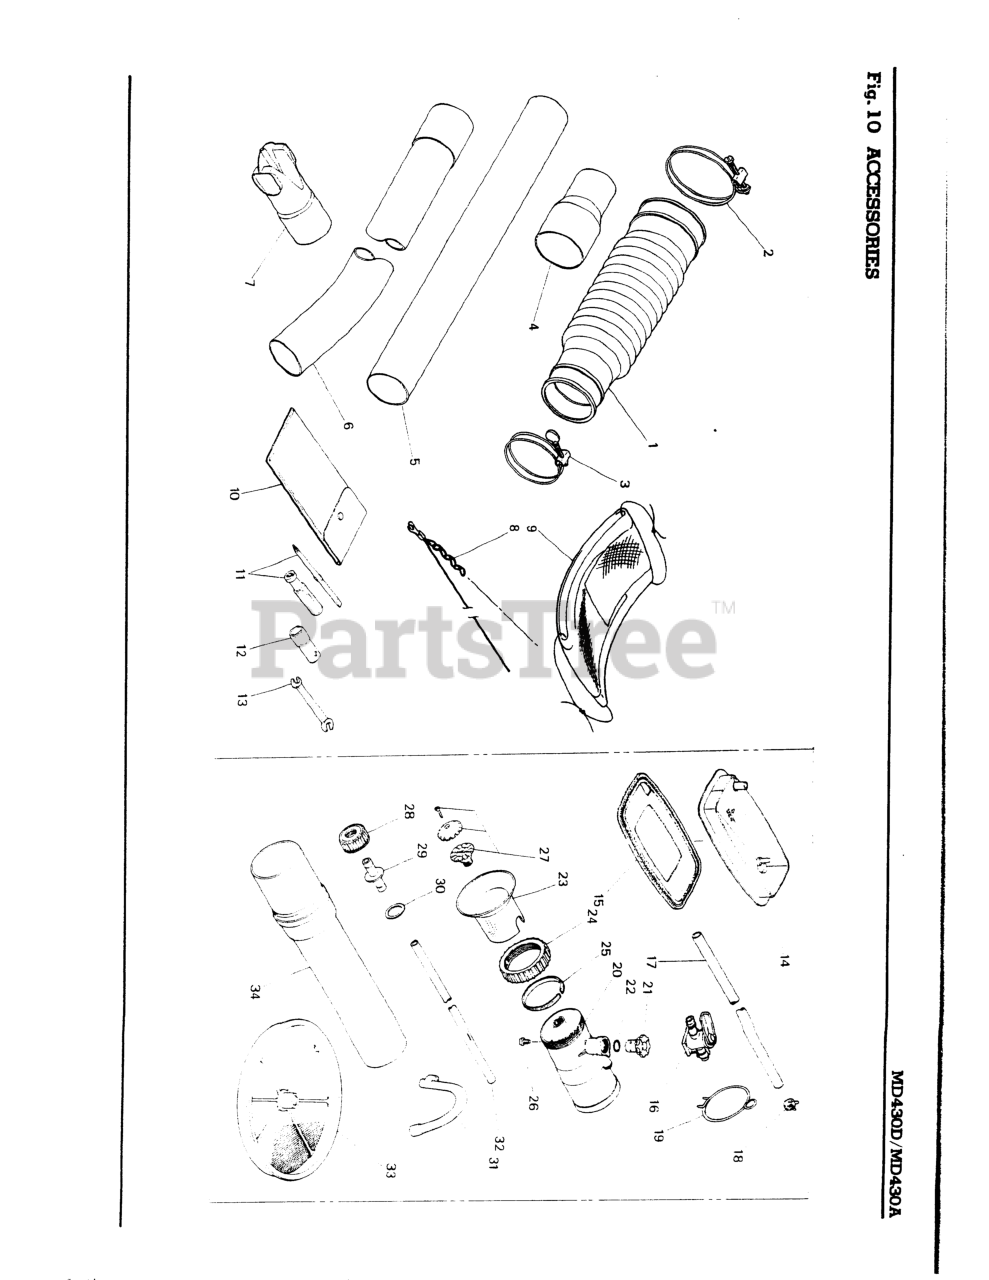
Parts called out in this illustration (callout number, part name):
2	2756-51510 (RPLS. 07280-09832)
5	PIPE (NLA)
11	SCREWDRIVER
14	COVER ASSEMBLY
16	COCK ASSEMBLY (NLA)
20	MIST PIPE ASSEMBLY
23	PIPE, SLIDE (NLA)
24	STOPPER (NLA)
26	SCREW, M5 X 10
